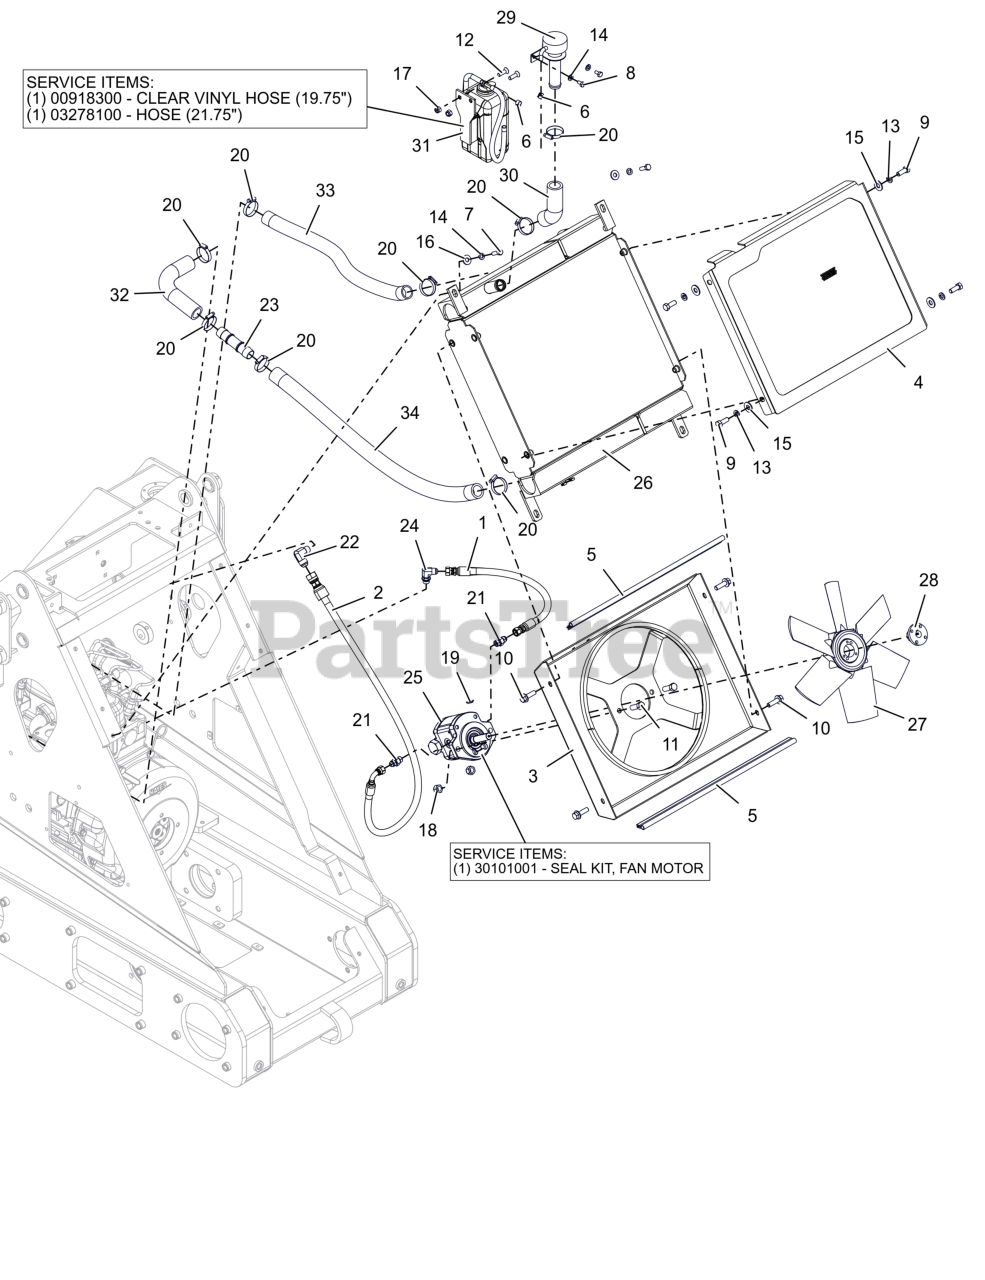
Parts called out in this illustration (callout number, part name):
1	HOSE, HYD .375" X 18.75" LG
2	HOSE, HYD .375" X 36.00" LG
3	MOUNT, FAN - RADIATOR (BLACK)
4	COVER, RADIATOR (BLACK)
5	SEAL, TRIM - 19.625"
6	CLAMP-HOSE, SPRING .188
7	BLT,HEX .31-18X1.00 G5 ZCC
8	BLT,HEX .25-20X.50 G5 ZCC
9	BLT,HEX .38-16X1.00 G5 ZCC
10	BLT, HEX-FLG 0.375-16X1.25 GR5 ZC120
11	BLT, HEX 0.4375-14X1.25 GR5 ZCC
12	SCR, MCH .312-18X1.00 SFH ZCC
13	WSHR,LK-REG .375X.094 ZCC
14	WSHR,LK-REG .312X.078 ZCC
15	WSHR,FLT .438X1.00X.083 ZCC
16	WSHR,FLT .375X.875X.083 ZCC
17	NUT,NYL .31-18 G5 ZCC
18	NUT, LK-NYL-FLG .44-14 GR5 ZCC
19	KEY, FAN MOTOR
20	CLAMP-HOSE 1.50X.81X1.42
21	FITTING, HYDRAULIC 6400 06-06
22	FITTING, HYDRAULIC 2501 08-08
23	CONNECTOR, HOSE - 1" COOLANT
24	FITTING, HYDRAULIC 9059 06-06
25	MOTOR, HYDRAULIC
25	SEAL KIT, FAN MOTOR
26	RADIATOR, COMBO
27	FAN, RADIATOR - 6 BLADE 13"
28	BUSHING, FAN
29	NECK, FILLER TUBE
30	HOSE, FORMED
31	TANK, OVERFLOW
31	HOSE,1/4 IN VINYL
31	1 INCH OF HOSE, .25 LOW-PERM BULK GAS
32	HOSE, RADIATOR - LOWER
33	COOLANT HOSE-LOWER 20"
34	COOLANT HOSE-LOWER 20"
